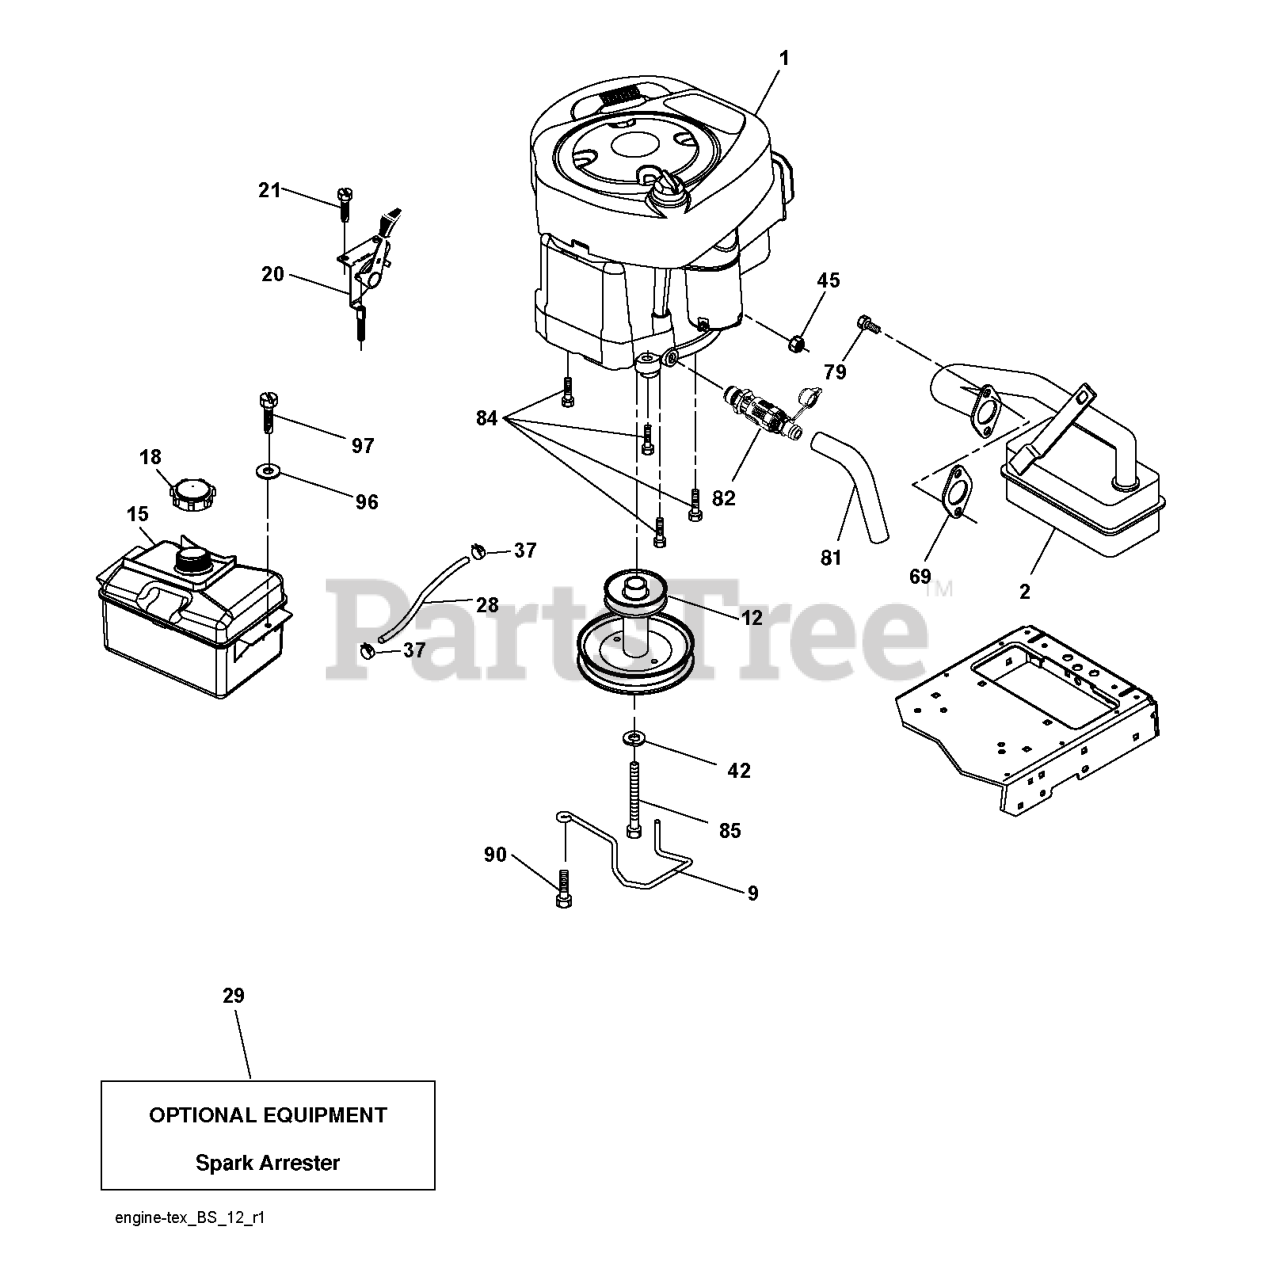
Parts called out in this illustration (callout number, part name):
2	MUFFLER.B&S.MODEL.21.11HP.OHV
9	KEEPER.BELT.ENGINE.3.25 (3 2)
12	PULLEY.ENG.CL.MECH.SLVR.LT/YT
15	RP TANK FUEL FRT 1.5 GAL
18	FUEL CAP
20	CONTROL.TH/CK.C.
21	SCREW.#10 X 0.750.BOS
28	LINE.FUEL.20
29	KIT.SPARK ARRESTOR 794945 B&S
37	HOSE CLAMP
42	LOCKWASHER
45	NUT
69	REPL BY 532 27 22-93
79	SCREW.SOCKET HD.5/16-1
81	TUBE, DRAIN OIL ASM.
82	VALUE.OIL.DRAIN
84	SCREW.3/8-16
85	BOLT HEX 7/16-20X4-1/4"
90	SCREW 3/8-16X1
97	SCREW HEXWSHR 1/4-20X3/4
